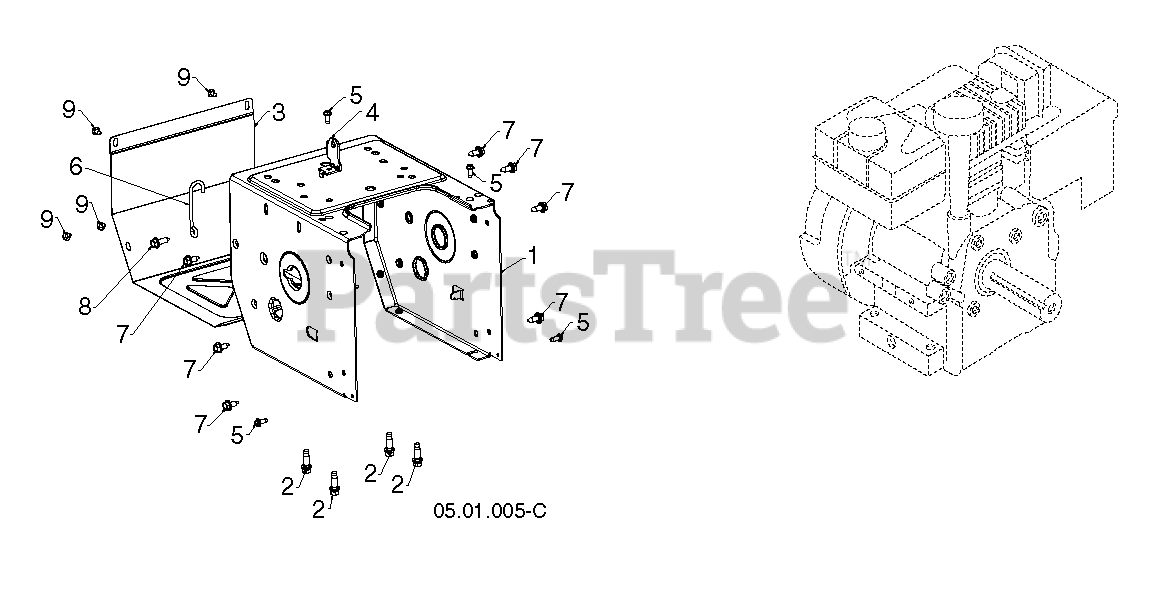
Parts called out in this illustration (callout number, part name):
2	BOLT 3/8-16X1-1/8
4	BRACKET.SHIFTER.BZP
5	SCREW 14-20 X 5/8
7	BOLT.HEX.HD.WASHER.5/16-18X.75
8	Hex Washer Head Bolt, 5/16-18 X 3/4 Thread Forming
